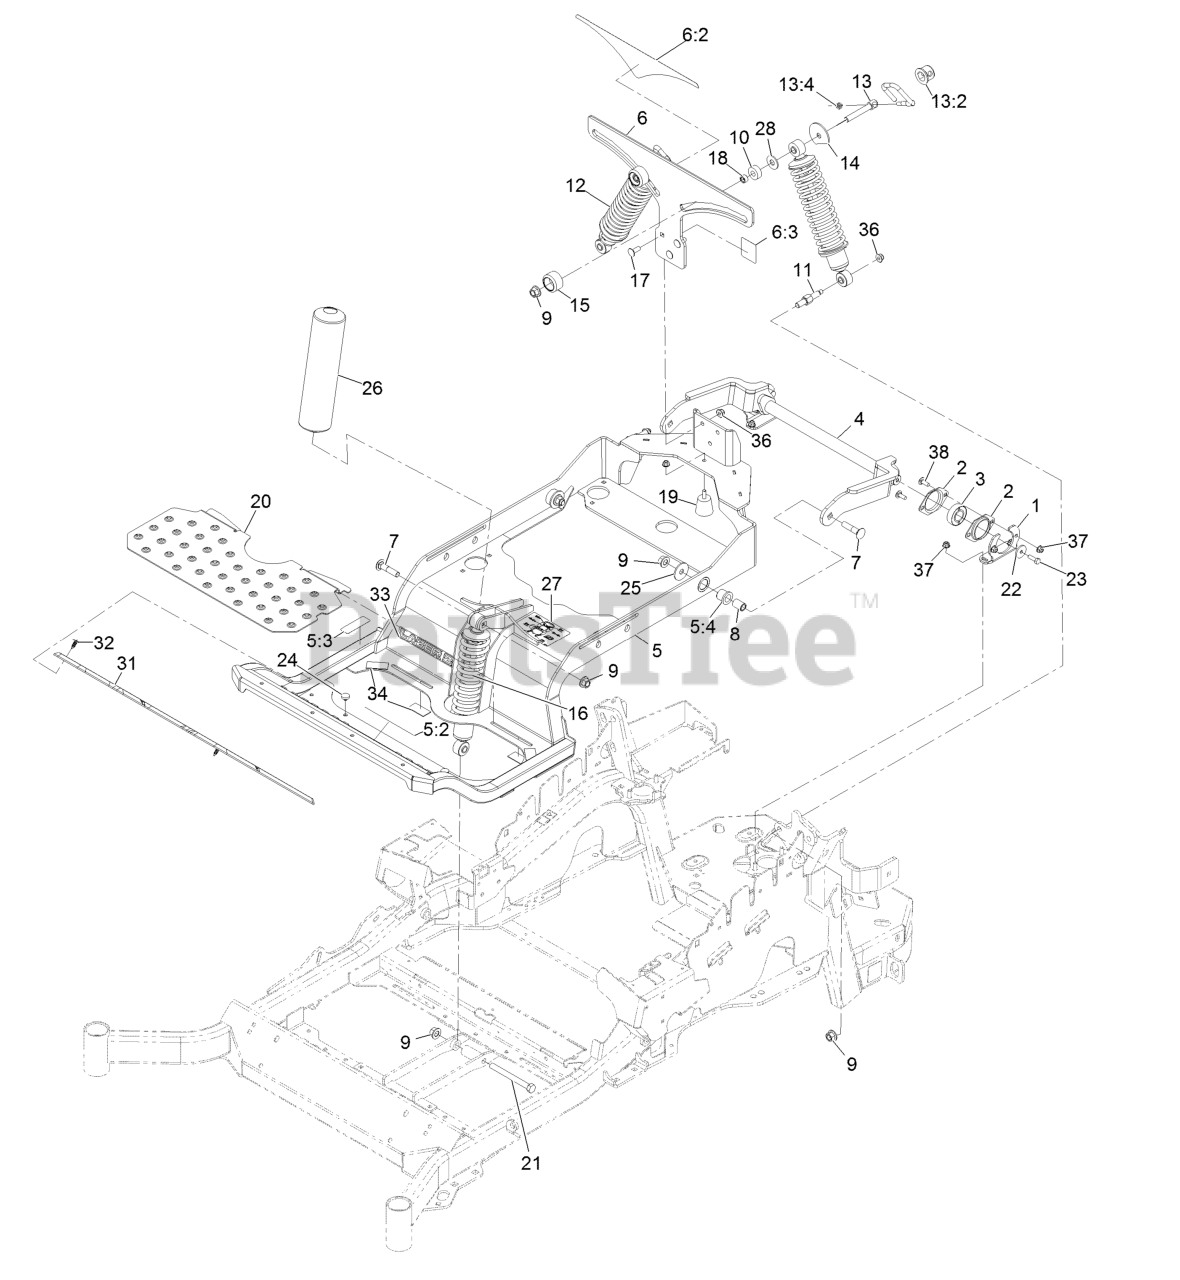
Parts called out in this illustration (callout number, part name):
1	Bracket-Bearing
2	Housing-Bearing, Flange
3	Bearing
4	Arm-Trailing
5	Subframe ASM
5:2	Decal-Danger
5:3	Decal-Brake, Parking
5:4	Bushing-Flange
6	Bracket-Mounting
6:2	Decal-Adjustment, Ride
6:3	Decal-Lock, Cam
7	Bolt-Carriage 1/2-13 X 2 1/4
8	Spacer-Aluminum
9	Nut-Lock 1/2-13
11	Bolt-Shoulder
12	Shock/Spring ASM
13	Cam Lock ASM
13:2	Cap-Lock
13:4	Nut-Hex Nyloc 5/16-18
14	Plate-Stop
15	Knob-Front
16	Shock/Spring ASM
17	Bolt-Carriage 3/8-16 X 1
18	Bearing-Needle
19	Bumper-Rubber
21	Screw-HH 1/2-13 X 5
22	Washer-Flat
23	Screw-HH 5/16-18 X 1 W/Patch
26	Cover-Shock
27	Decal-Service Aid
28	Washer
31	Floor Mat
32	Plug-Plastic
33	Decal-Lazer Logo
34	Pad-Rubber
36	Nut-Nyloc 3/8-16 Flg
37	Nut-Nyloc 5/16-18 Flg
38	Bolt-Carriage 5/16-18 X 7/8
